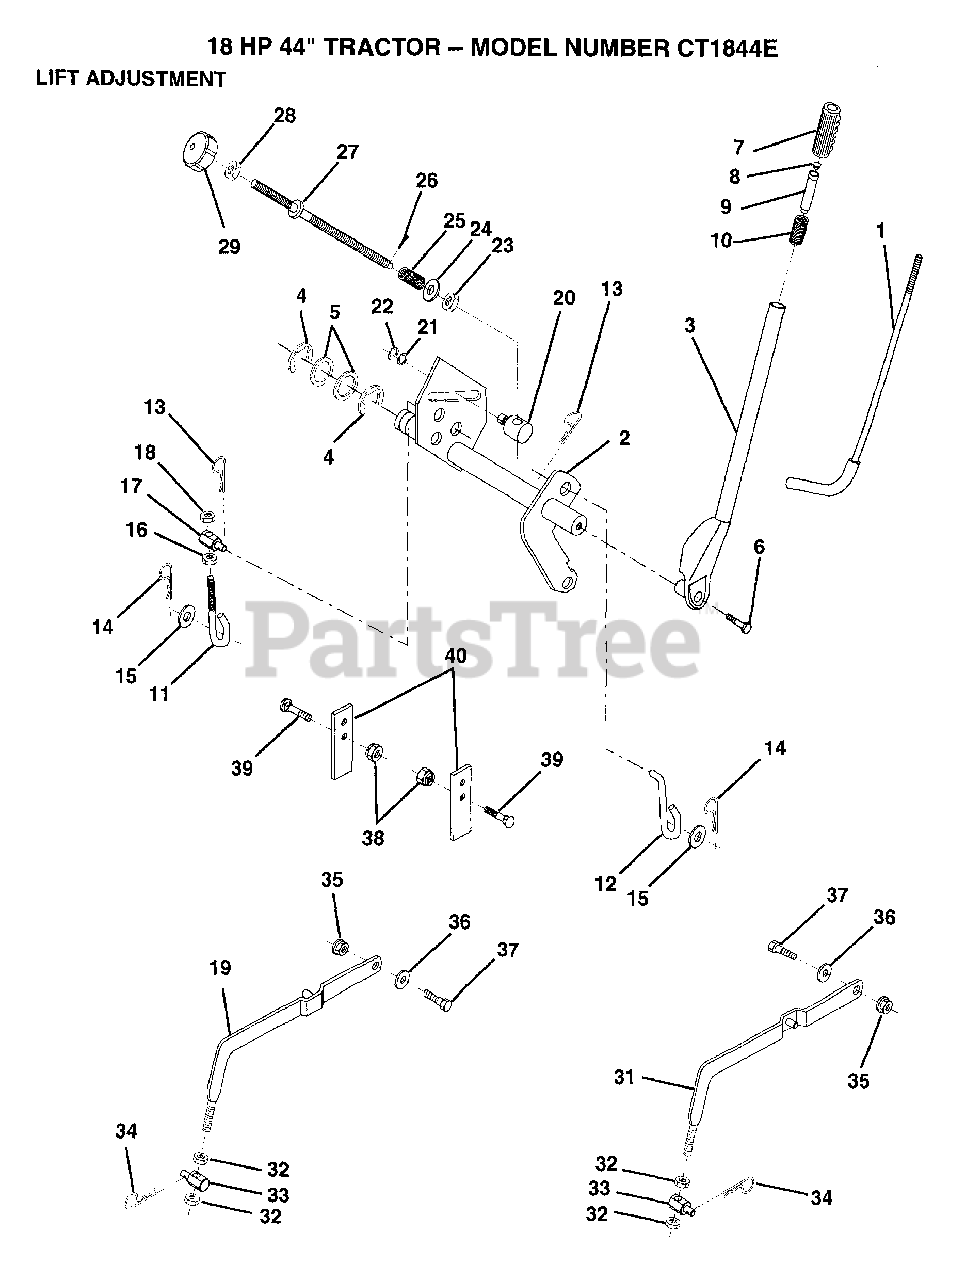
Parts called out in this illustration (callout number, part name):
1	LEVER ROD LT
4	E-RING
5	WASHER
6	"BOLT,HEX"
7	GRIP
10	SPRING T
11	PIVOT PIN T
12	LIFT LINK LT
14	SPRING.RETAINER
16	NUT
19	LH SUSP ARM ASM
20	TRUNION LT
21	WASHER
22	KLIP RING
23	NUT T
24	WASHER
25	SPRING T
27	ROD LIFT LT
28	NUT
29	KNOB INF 3/8-16
31	RH SUSP ARM ASM
32	NUT
34	SPRING H
35	NUT SPECIAL T
36	WASHER T
37	"BOLT, SHOULDER LT"
40	UPSTOP
